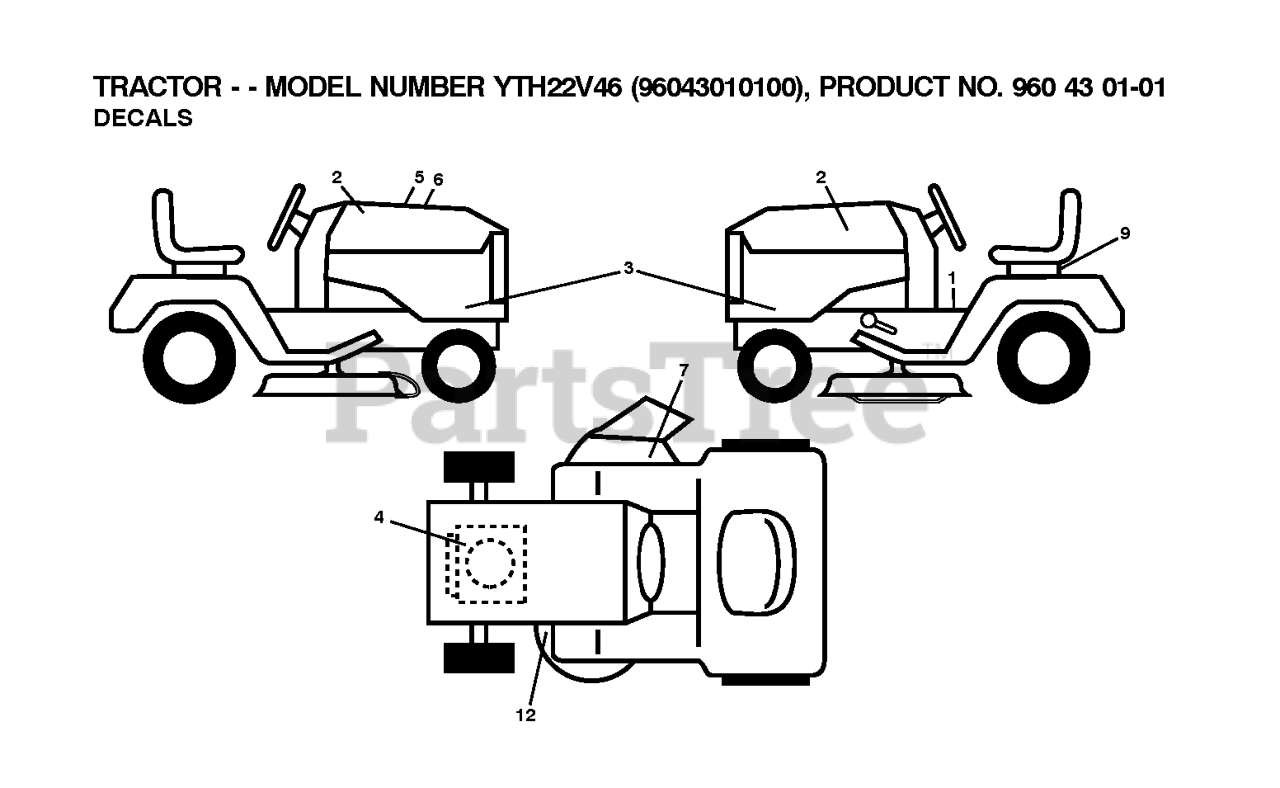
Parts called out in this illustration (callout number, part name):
1	DECAL.FENDER.WARNING.ENG
2	DECAL.HOOD.LOGO.ORANGE.HUSQVAR
3	DECAL.SDPNL.YTH22V46.BS.HUSQ
4	DECAL.ENG.BS.22.XRD.TWN.278445
5	DECAL.WARNING.CUST.RESP.E85.
6	DECAL.RPL.
7	DECAL.WARN.KEEP.HAND.AWAY
9	DECAL BTRY SYMBOLS
12	DECAL V BELT SCHEMATIC
